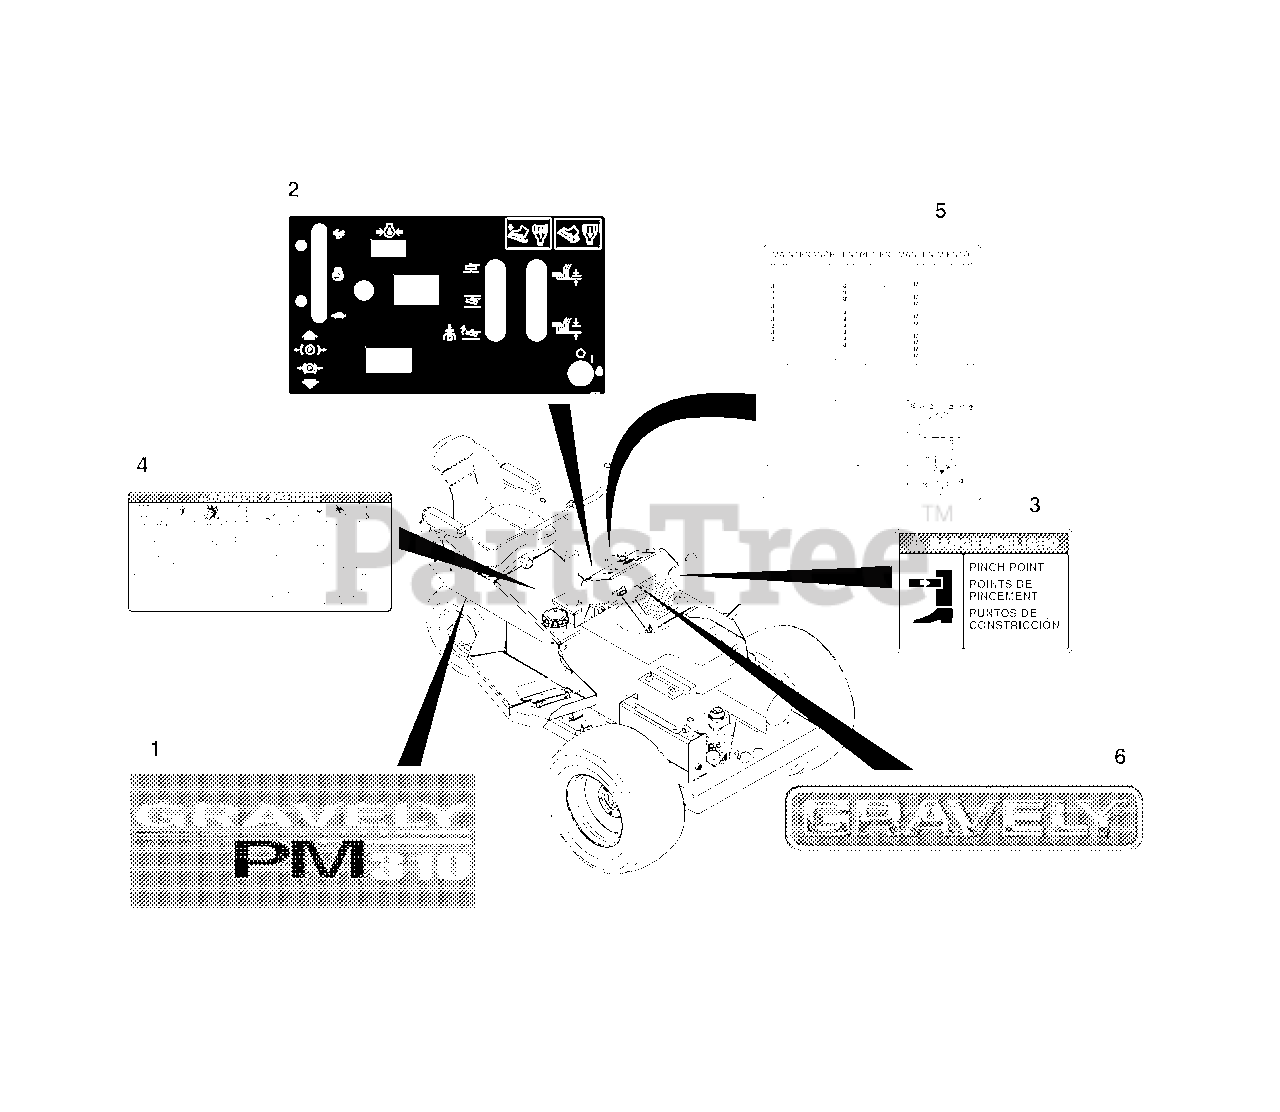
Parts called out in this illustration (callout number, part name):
1	Decal, PM-310
2	Decal, PM-310 Panel
3	Decal, Pinch Point
4	Decal, PM-310 Danger
5	Decal, PM-310 Maintenance
6	Decal, Gravely Logo
